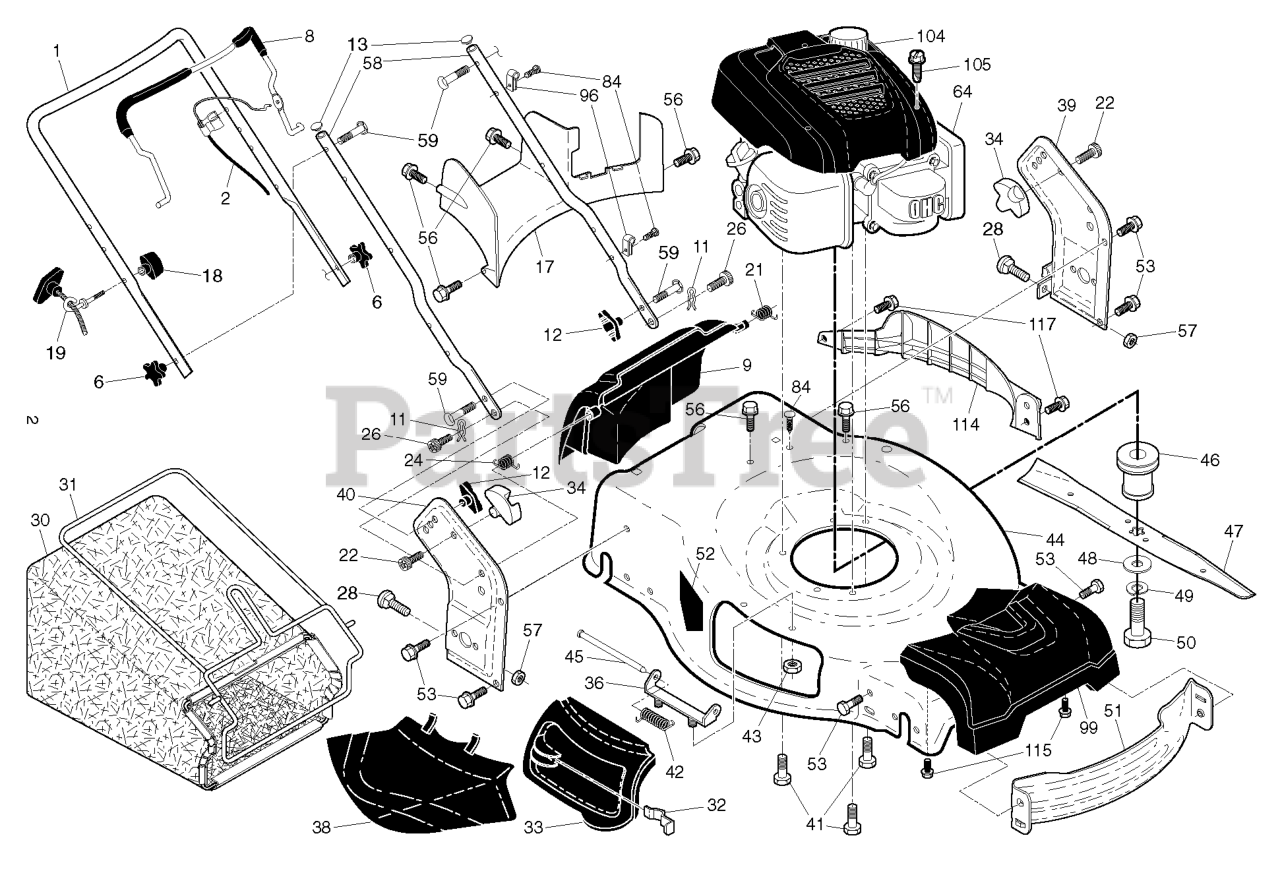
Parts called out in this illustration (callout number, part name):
1	HANDLE.UP.3POS.BS.AW2.GREY
2	CABLE.MZR.ZONE.CONTROL
6	KNOB.HANDLE.PLASTIC.STAR.BLACK
8	BAIL.OM.ERGO.BENT.MZR.ORAN.668
9	DOOR.REAR.ASM.22+.HUSQ.F/RG.CE
11	COTTER.HAIRPIN.DOOR/HANDLE.PIV
12	KNOB, DEFLECTOR
13	PLUG.PLASTIC.7/8".14-20.GAUGE
17	BAFFLE.REAR.22+RGD.AWD.PLASTIC
18	T-KNOB.NEW ROPE GUIDE
19	GUIDE.ROPE.BLK.ZINC.CHROM
21	SPRING.LH.BLACK
22	SCREW.PAN.HEAD.#10
24	SPRING.RH.GRAY
26	SCREW,DOOR/HANDLE.PIVOT
28	BOLT.CARRIAGE.LN.5/16-18X.5/8
30	GBAG.BA85028EM.NOFRAME.GRY/SLV
31	FRAME.GBAG.22+.BLK
32	LATCH.DOOR.ZINC
33	DOOR.MULCH.22 PLUS.HUSQ.GREY
34	BRACKET.GRASSBAG.ATTACHING.BLK
36	BRACKET.ASM.HINGE.21.FWGD.
38	DEFLECTOR.CLIPPING.22.BLACK
39	BRACKET.ASM.HANDLE.LT.22+.GREY
40	BRACKET.ASM.HANDLE.RT.22+.GREY
41	BOLT 3/8-16X1-1/8
42	SPRING.TORSION
43	NUT.FLANGE.1-4-20-SERR
44	KIT.HSG.22+AW.MC.WO.668.CE SYM
45	ROD.HINGE.21
46	ADAPTER.BLADE.25MM.3MPH
47	BLADE.22+4N1.2PIN.5STAR.(P07)
48	WASHER,HARDEN
49	LOCKWASHER
50	SCREW, HEX HD 3/8-24 X 1-3/8
51	BAFFLE.FRONT.22.PLUS
52	DECAL.INTERNATIONL.CUTFINGER
53	BOLT.5/16HEX.WHS.HD
56	SCREW.HX.13X.750
57	NUT.FLANGE.5/16
58	HANDLE.LOWER.22+.BT.GRAY
59	BOLT, HANDLE 5/16-18X1.75
84	FASTENER.PUSH.O.250X0.783
96	CLIP.CABLE.BLK
99	COVER.ASSEMBLY.FRONT.22+AWD
104	SHROUD.ASM.HONDA.HUSQVARNA
105	SCREW.SHROUD.HONDA
114	BUMPER.LEFT SIDE 22+.MS498
115	SCREW.SHOULDER.5/16X1.375
117	BOLT.HEX.HD.WASHER.5/16-18X.75
